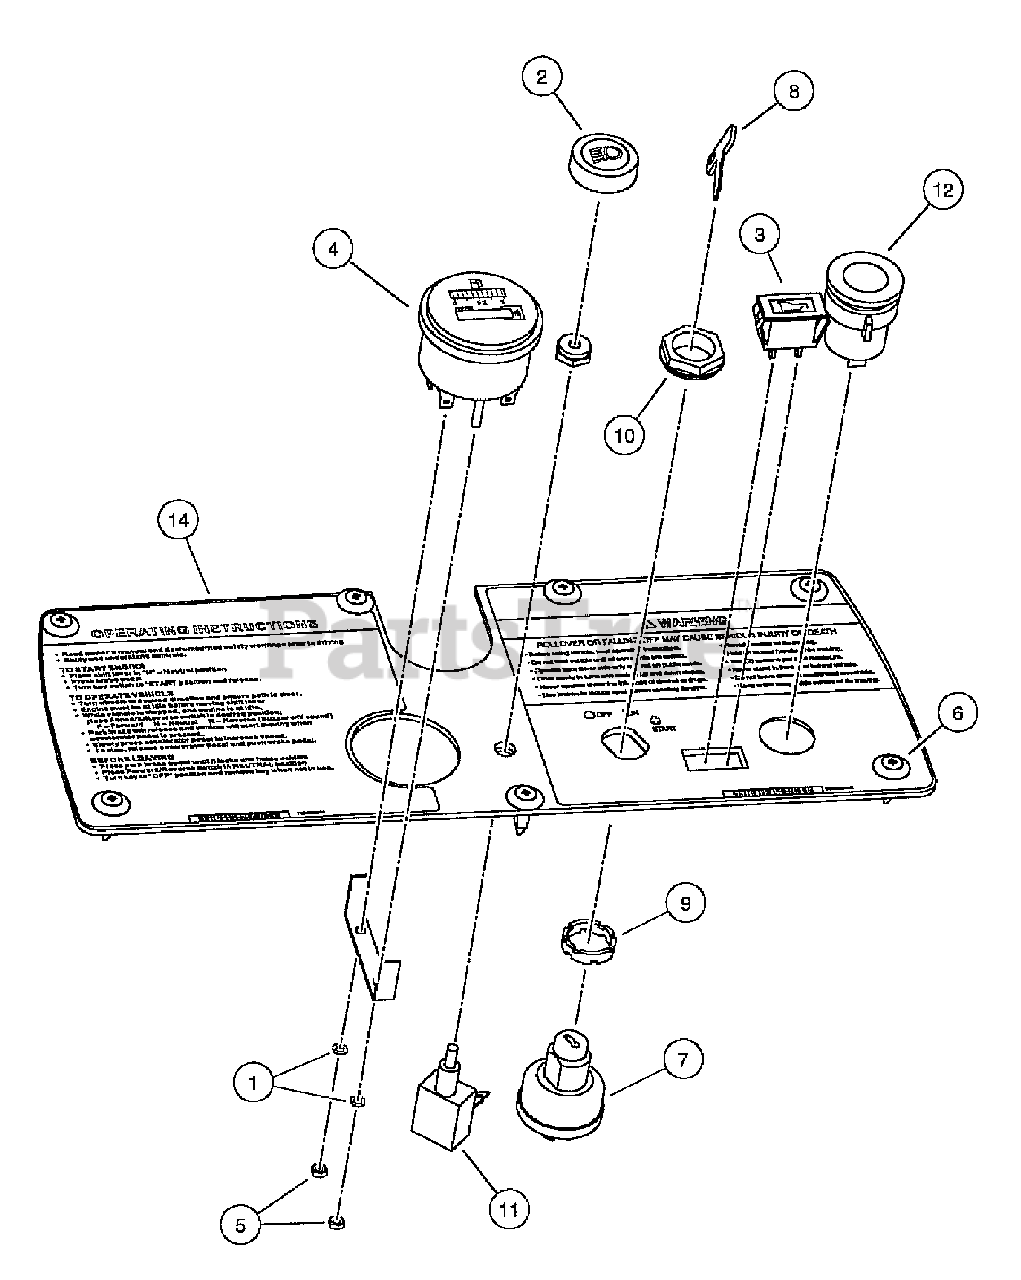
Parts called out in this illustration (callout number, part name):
1	Lockwasher, M4
2	Knob, Light Switch
3	Light, Oil
4	Gauge, Fuel/Hour, with Bracket
5	Nut, M4-.7
6	Screw, Tuflok Panel, 1/4
7	Key Switch 12v Key Start
8	Key Set (1 pair)
9	Spacer, Keyswitch
10	Nut, Key Switch
11	Switch, Light
12	Receptacle, Accessory
13	Panel, Instrument
14	Panel, Instrument (with 12-Volt Accessory Outlet Cutout)
